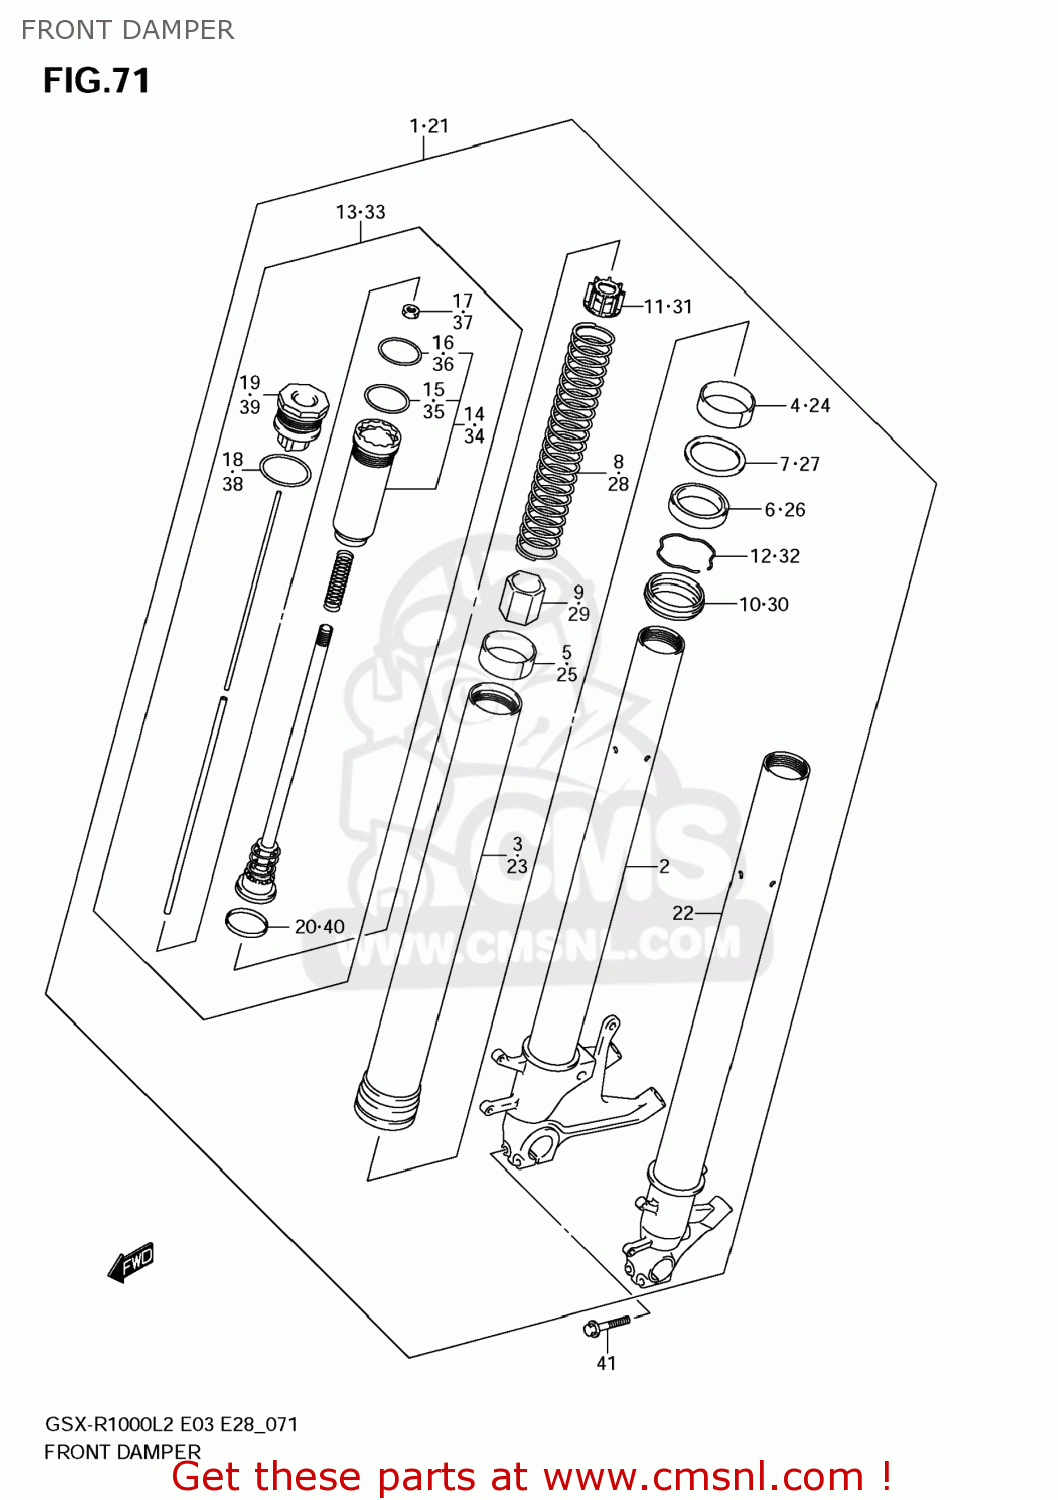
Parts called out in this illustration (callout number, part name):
1	DAMPER ASSY,FR FORK,R
2	TUBE,INNER,R
3	TUBE,OUTER
4	BUSH,GUIDE
5	BUSH,SLIDE
6	SEAL,OIL
7	SPACER,SEAL
8	SPRING
9	COLLAR,SPRING
10	SEAL,DUST
11	COLLAR,SPRING
12	CIRCLIP,FORK OIL SEAL
13	ROD,PISTON
14	CASE,ROD GUIDE
15	RING,PISTON
16	O RING
17	NUT
18	O RING
19	BOLT
20	RING,PISTON
21	DAMPER ASSY,FR FORK,L
22	TUBE,INNER,L
23	TUBE,OUTER
24	BUSH,GUIDE
25	BUSH,SLIDE
26	SEAL,OIL
27	SPACER,SEAL
28	SPRING
29	COLLAR,SPRING
30	SEAL,DUST
31	COLLAR,SPRING
32	CIRCLIP,FORK OIL SEAL
33	ROD,PISTON
34	CASE,ROD GUIDE
35	RING,PISTON
36	O RING
37	NUT
38	O RING
39	BOLT
40	RING,PISTON
41	BOLT
